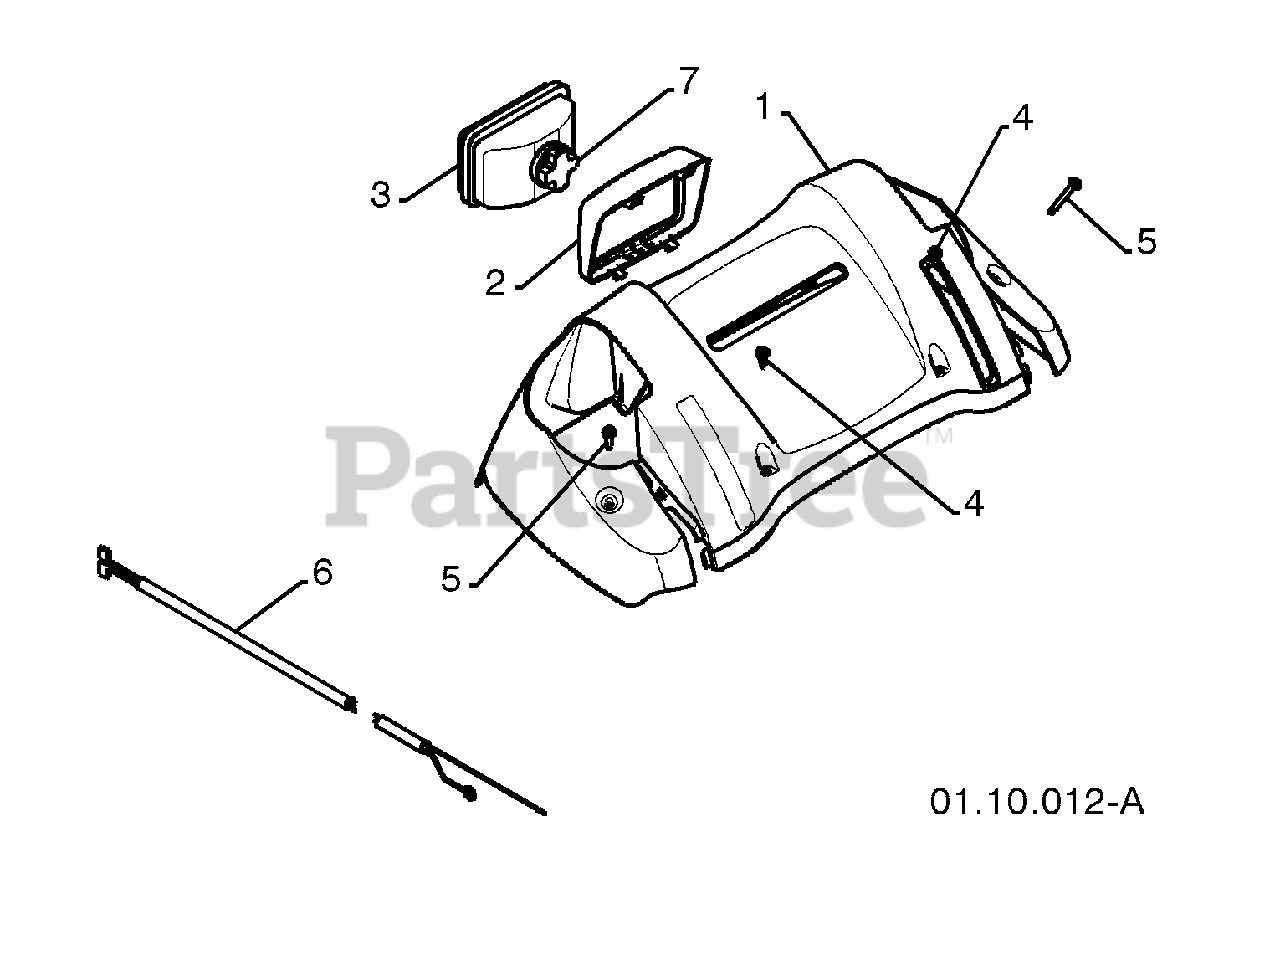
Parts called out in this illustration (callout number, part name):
1	CONSOLE PANEL GRAY
2	HEADLIGHT BEZEL GRAY
3	FLOOD HEADLIGHT
4	SHOULDER SCREW 10-24 X .625
5	SCREW 10-24 X 1.25
6	WIRE HARNESS
